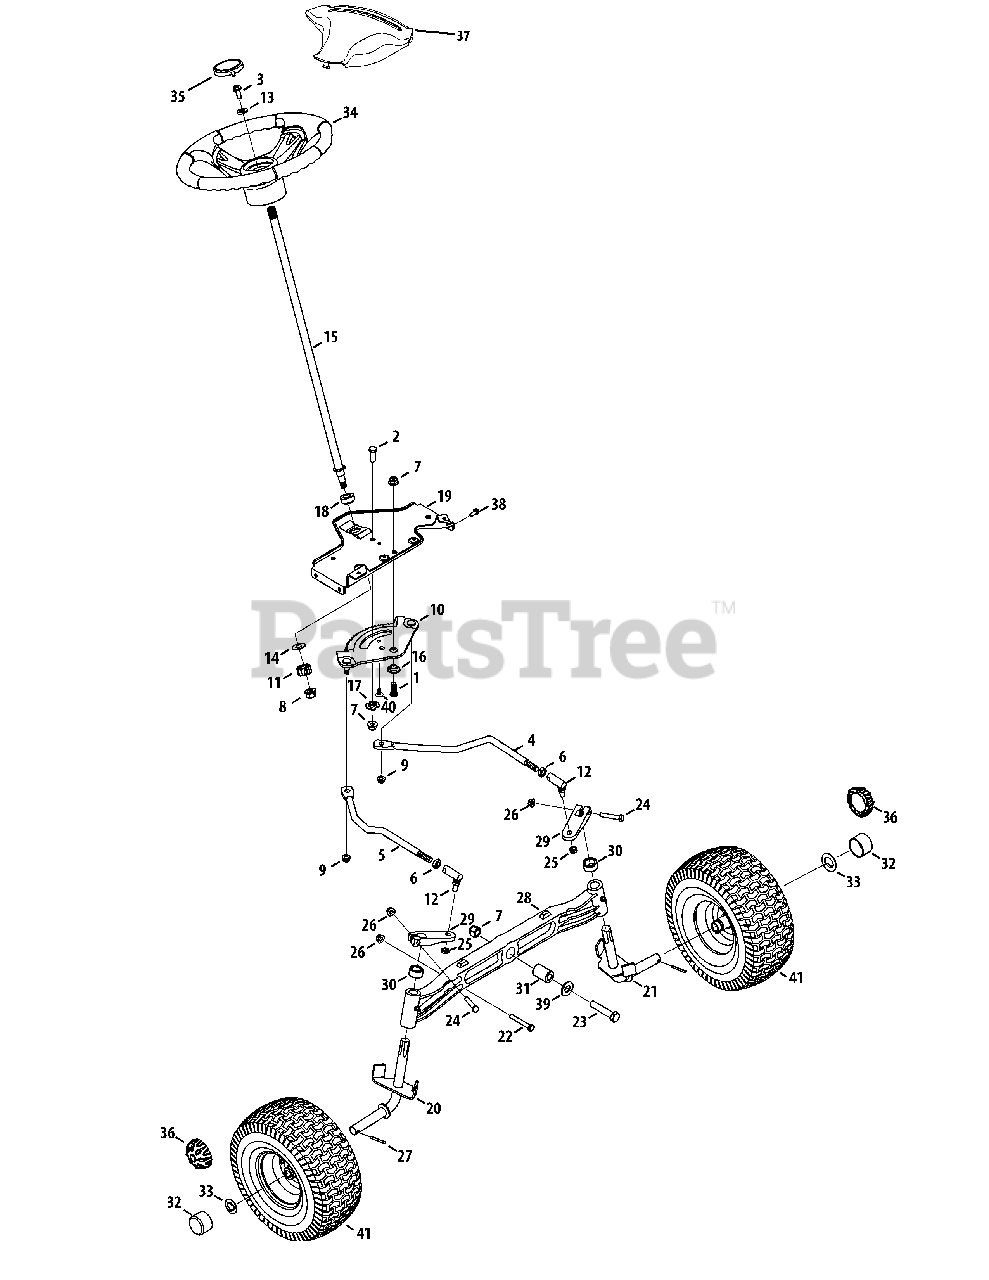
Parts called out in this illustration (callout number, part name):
1	Screw, 3/8-16 x 1.0
2	Hex Screw 3/16 x 1.00
3	Hex Screw 5/16-18 x 1.00 Special
4	Link, Drag LH
5	Link, Drag RH
6	Hex Jam Nut 7/16-20
7	Flange Lock-Nut 3/8-16 Gr. F Nylon
8	Flange Lock Nut, 7/16-20
9	HEX FLANGE NUT
10	Steering Gear, 11/90 Ratio
11	Steering Pinion Gear
12	Ball Joint, 7/16 - 20
13	Flat Washer .406 ID x .875 DE x .105
14	Flat Washer .510 x 1.120 x .060
15	Steering Shaft .625 OD x 24.25
16	Shoulder Spacer .385 x 1.25 x .3025
17	Spacer .38 x 1.375 Special
18	Hex Flange Bearing 5/8
19	Steering Support Bracket
20	Axle Ass'y RH .750 Dia. (50" Deck)
20	Axle Ass'y RH .750 Dia. (54" Deck)
21	Axle Ass'y LH .750 Dia. (50" Deck)
21	Axle Ass'y LH .750 Dia. (54" Deck)
22	Hex Bolt 5/16-18 x 2.25
23	Hex Cap Screw, 3/8-16 x 2.5
24	Hex Screw 5/16-18 x 1.75" Lg.
25	Hex Cent L-Nut 3/8-24
26	Flange Locknut 5/16-18 Gr. F, Ny lon
27	Cotter Pin 5/32" Dia.
28	Pivot Bar (cast)
29	Steering Block
30	Spacer .710 ID x .125 OD x .56
31	Spacer .385 x 1.0 x 1.5075
32	Hub Cap (w/plastic bearings)
32	Hub Cap (w/ball bearings)
33	Flat Washer .755 x 1.92 x .060 (w/ball bearings)
34	Steering Wheel, Standard Grip
34	Steering Wheel, Softgrip
35	Steering Wheel Cap (spig) logo
36	Hub Cap
37	Steering Wheel Cover (w/o sprigs)
38	SCREW 5/16-18 x .750
39	Flat Washer .406 x .875 x .059
40	Rachet Clip
41	See Wheel Chart
